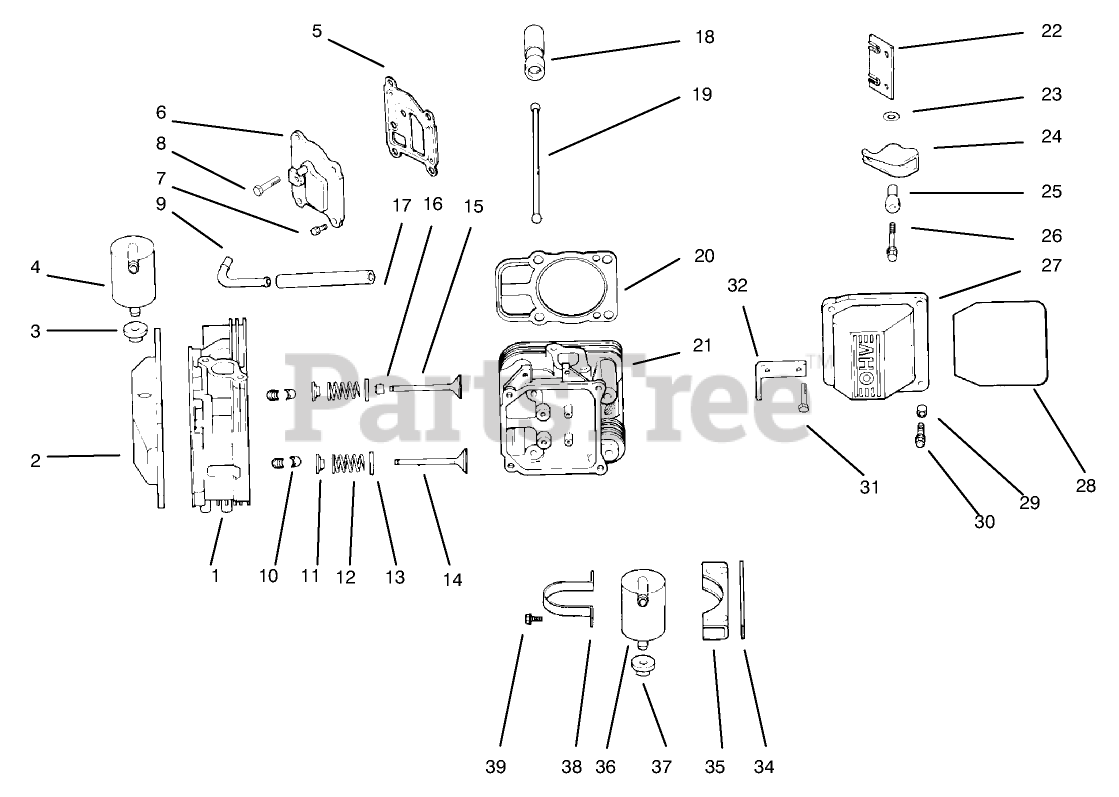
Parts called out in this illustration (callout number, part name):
1	#1 Cyl. Head Asm
2	Kit-Valve Incl 6 20-22
3	Grommet-Rubber
4	Kit-Breather INC 4
5	Gasket-Breather
6	Cover-Breather
7	Screw
8	Plug
9	Fitting
10	Retainer Kit
11	Cap-Spring, Valve
12	Spring-Valve
13	Retainer-Spring
14	Valve-Exhaust
14	Valve-Exhaust (.25)
15	Valve-Intake
15	Valve-Intake (.25)
16	Seal-Stem, Valve
17	Hose
18	Lifter-Valve
19	Rod-Push
20	Gasket-Cylinder Head
21	#2 Cyl. Head Asm,
22	Plate-Guide
23	Washer
24	Arm-Rocker
25	Pivot-Rocker Arm
26	Screw
27	Valve Kit
28	"O"Ring
29	Spacer
30	Screw
31	Screw
32	Strap-Lifting
33	Kit-Breather Incl 3-9
34	Spacer
35	Bracket
36	Separator-Oil Breather
37	Grommet
38	Strap-Lifting
39	Screw
